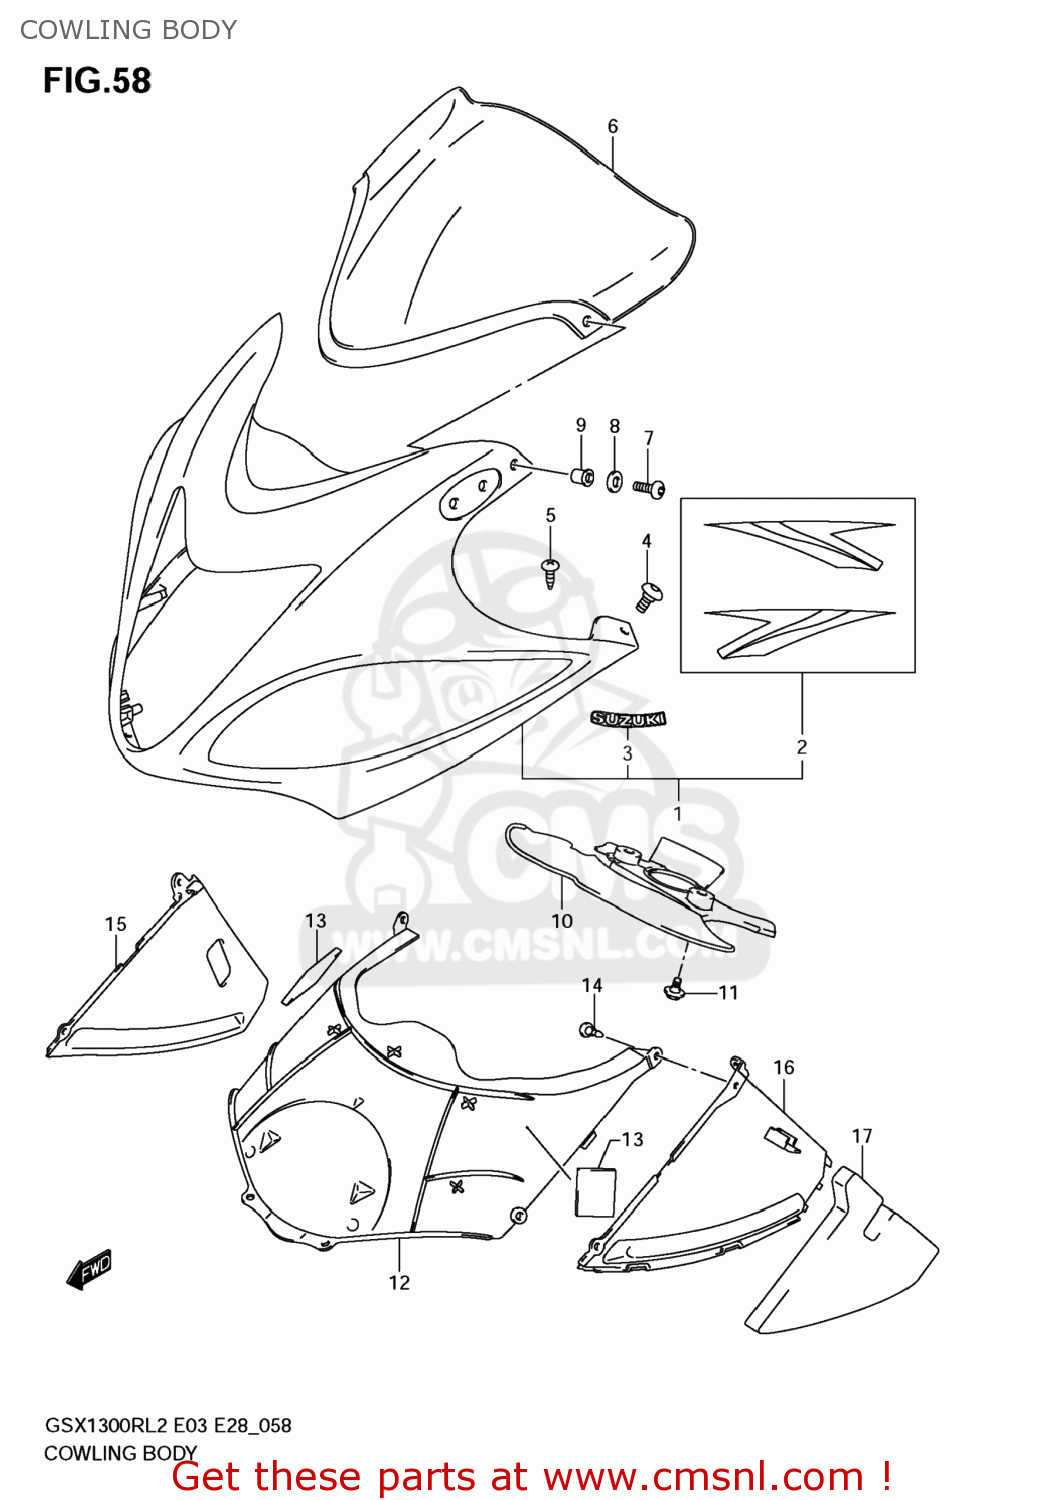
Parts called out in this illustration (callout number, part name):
1	COWLING ASSY,BODY
2	TAPE SET,BODY COWL
3	EMBLEM,SUZUKI
4	SCREW(5X16)
5	SCREW(5X16)
6	WINDSCREEN
7	SCREW(5X14)
8	WASHER
9	NUT
10	COVER,LWR BRACKET
11	BOLT(6X12)
12	COVER,BODY COW
13	COVER
14	CLIP(BLACK)
15	COWLING,UNDER INNER,R
16	COWLING,UNDER INNER,L
17	CUSHION,INNER COWL,L
